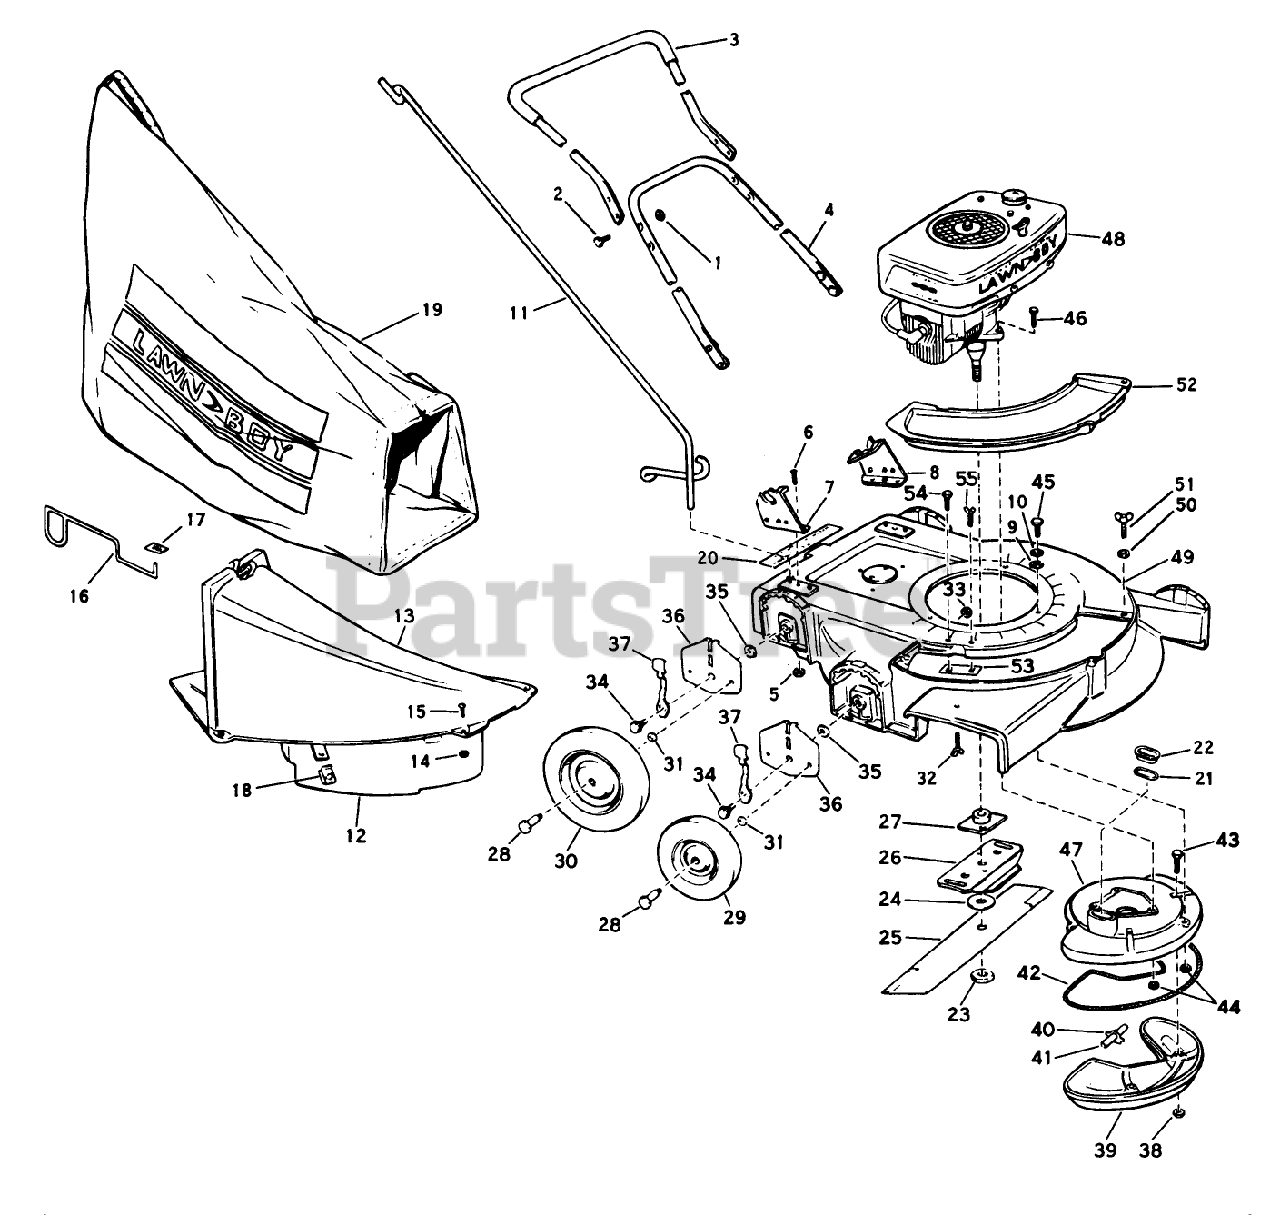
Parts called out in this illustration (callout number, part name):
1	STOP NUT
3	Handle Grip Assy. Top
6	SCREW S
12	Skirt Assembly-Chute (Includes Hardware)
13	Chute and Spring Assy. (Includes Hardware)
18	SPEED NUT ARDEN
19	89802 LB WHOLE GOODS
20	Decal, Instruction
23	NUT-BLADE
27	PLATE AND COLLAR ASM
28	BOLT WHEEL
31	WASHER WROUGHT
38	LOCKNUT E
40	Gasket-Internal Tube
41	Tube-Internal Muffler
49	Housing Cover Assy. 21"
